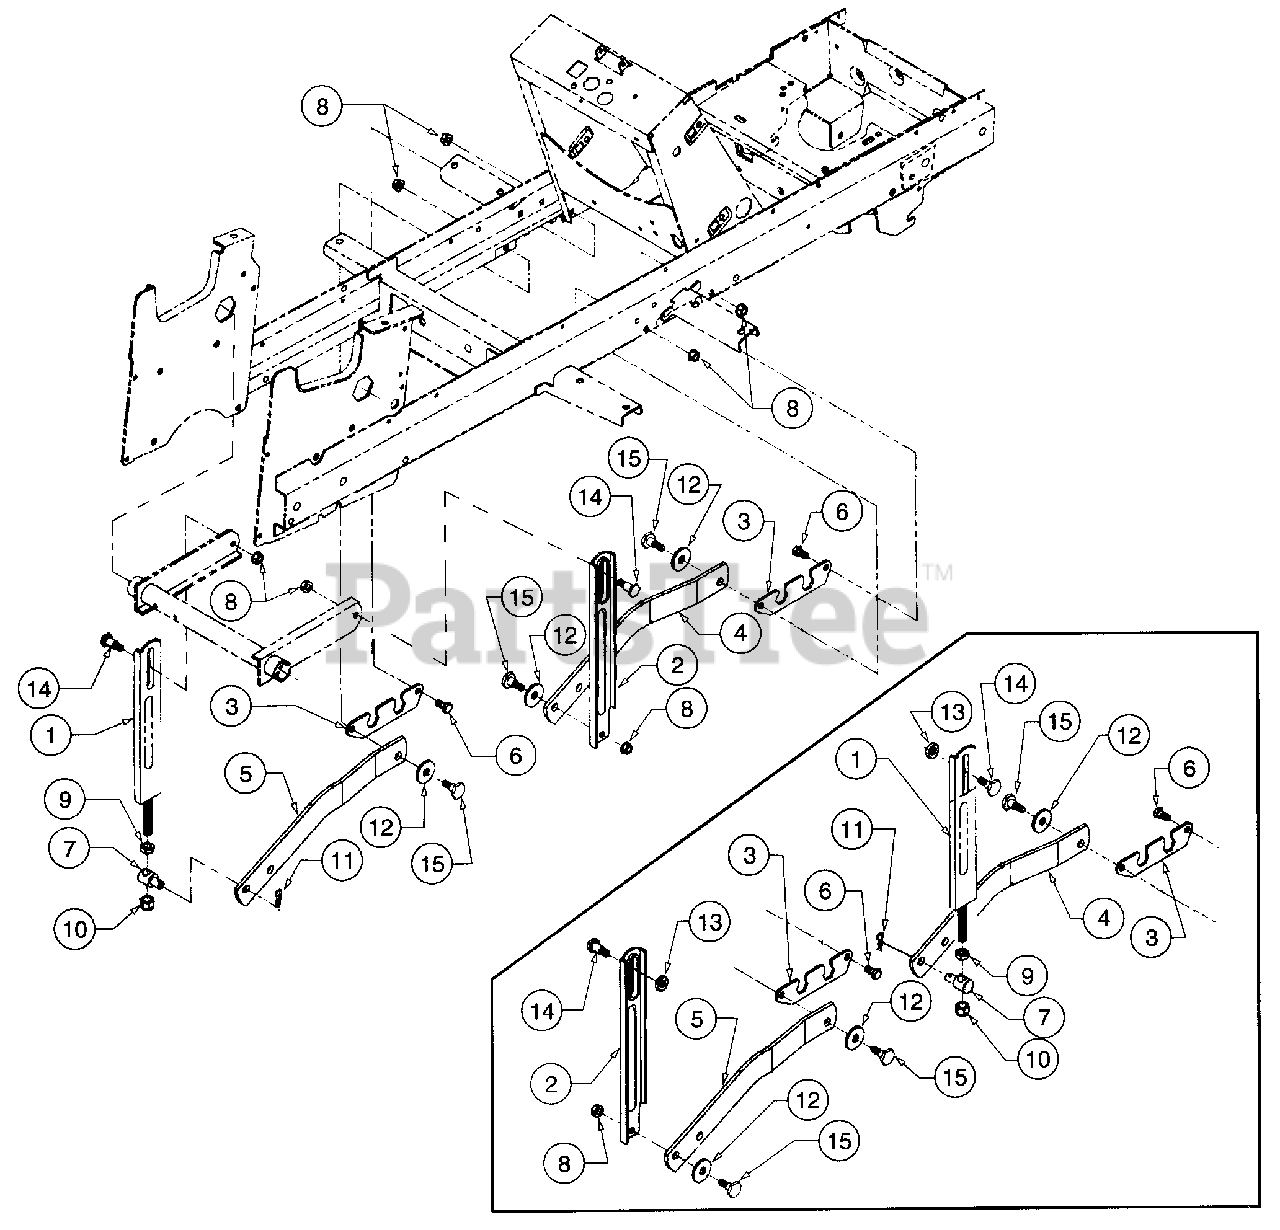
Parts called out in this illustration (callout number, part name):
7	Ferrule, Adjustment
8	Nut, Hex Flange Lock, 3/-16
9	Nut, Hex Jam, 1/2-13 GR5
10	Nut, Hex Insert Lock, 1/2-13
11	Pin, Internal Cotter
12	Washer, Flat, .50 x 1.5 x .15
13	Washer, Flat, .531 x .875 x .15
14	Bolt, Shoulder
15	Bolt, Shoulder
